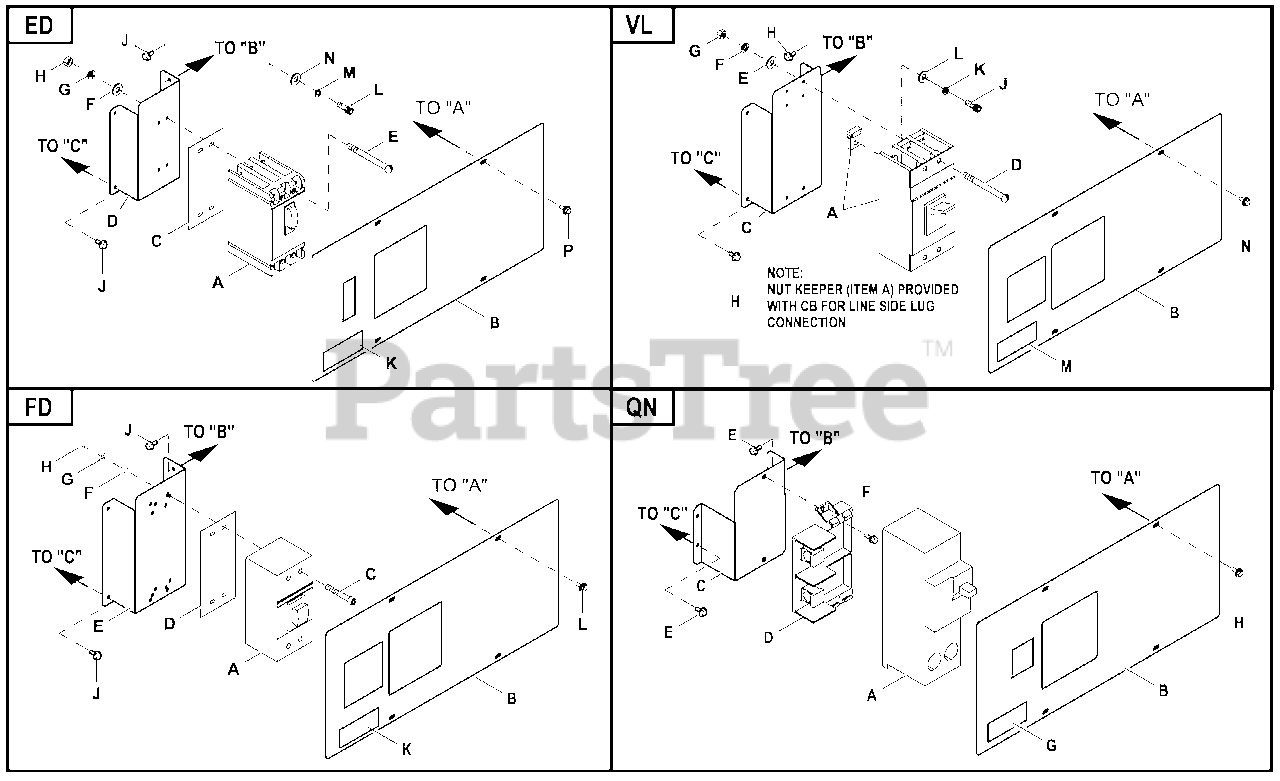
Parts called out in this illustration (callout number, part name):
A	CB 0060A 3P 480V S ED4 LL
B	COVER PLATE CNTRL PNL ED
C	INSULATOR CB S(ED-3P)
D	STANDOFF CB MOUNT CONBOX
E	SCREW RHM #10-32X4-1/2
F	WASHER FLAT #10 ZINC
G	WASHER LOCK #10
H	NUT HEX #10-32 STEEL
J	SCREW HWHTF M6-1.0X 16
K	DECAL TERMINAL SHOCK HZD BI
L	SCREW SHC 1/4-28 X 3/4 G8.8 NZ
M	WASHER LOCK M6-1/4
N	WASHER-STEP 1/2ODX9/32ID BRASS
P	SCREW HWHT M6-1 X 16 N WA Z/JS
A	CB 0300A 3P 600V S JG-VL LL
B	COVER PLATE CNTRL PNL 400AF 3P
C	STANDOFF CB MOUNT CONBOX
D	SCREW RHM 10-32X4
E	WASHER FLAT #10 ZINC
F	WASHER LOCK #10
G	NUT HEX #10-32 STEEL
H	SCREW HWHTF M6-1.0X 16
J	SCREW SHC M8-1.25 X 20 C12.9
K	WASHER LOCK M8-5/16
L	WASHER FLAT 5/16-M8ZINC
M	DECAL TERMINAL SHOCK HZD BI
N	SCREW HWHT M6-1 X 16 N WA Z/JS
A	CB0150A3P 600V SFD6 LL
C	SCREW SHC 1/4-20 X 4.5 G8.8 NZ
D	INSULATOR CB FD FRAME 30MIL
E	STANDOFF CB C2 ET KG JG
F	WASHER FLAT 1/4-M6 ZINC
G	WASHER LOCK M6-1/4
H	NUT HEX 1/4-20 STEEL
L	SCREW HWHT M6-1 X 16 N WA Z/JS
A	CB0150A2P 240V SQN2 LL
B	CONBOX CONTRL COVER PNL
C	CB STANDOFF G 225AF 3P
D	BASE, QN CIRCUIT BREAKER
E	SCREW HWHTF M6-1.0X 16
F	SCREW HHTT M5-0.8X10BP
G	DECAL TERMINAL SHOCK HZD BI
H	SCREW HWHT M6-1 X 16 N WA Z/JS
